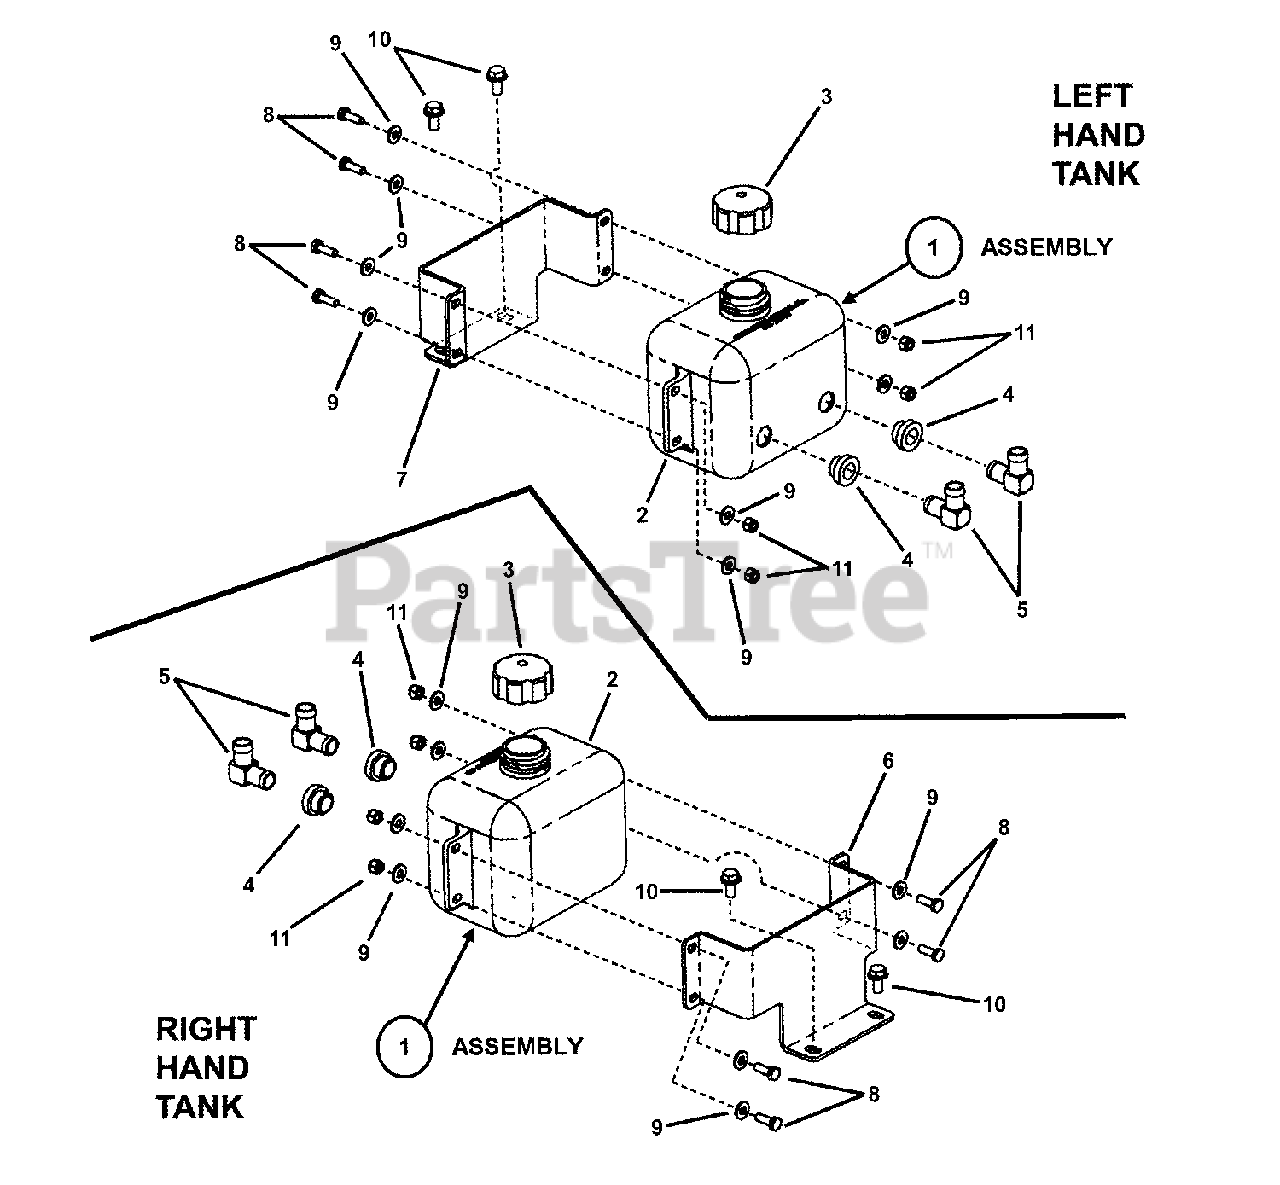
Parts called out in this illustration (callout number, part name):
1	ASSY, Hydraulic Tank (Includes 4 items shown below)
2	TANK, Hydraulic, NZM
3	CAP, Vented (Kelch # H4550D)
4	GROMMET (Dapco # 12078)
5	ELBOW FITTING (Dapco # 12183)
6	BRACKET, R.H. Hydro Tank Mount
7	BRACKET, L.H. Hydro Tank Mount
8	BOLT, 1/4-20 X 1" GD5 CZ
9	WASHER, 1/4" Flat
10	SCREW, 5/16-18 x 5/8" Hex Washer Self-Tap
11	NUT, 1/4-20 HEX NYLON LOCK
